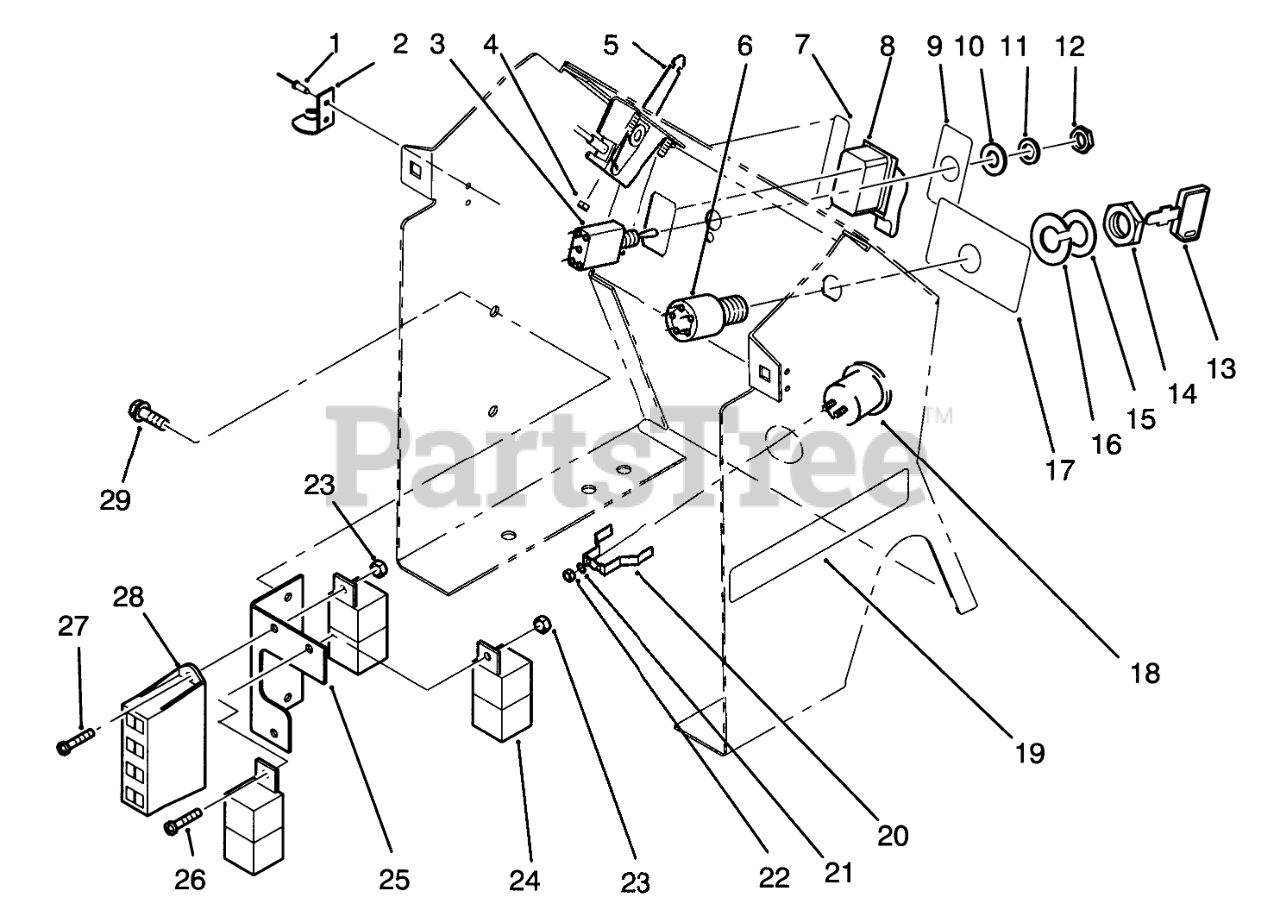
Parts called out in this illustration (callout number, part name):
1	POPRIVET 1/8X 1/8 BK
2	KEEPER-LATCH
3	Switch-Lights (Incl. Ref. #10-14 )
5	CONTROL-THROTTLE
6	Switch-Ignition, Assembly (Incl. Ref #13, 14 & 16)
7	DECAL-PTO
8	PTO-SWITCH W/COVER
9	DECAL-LIGHTS
10	TAB-WASHER
11	Washer
13	KEY-IGNITION
15	Washer
16	LOCKWASHER
17	DECAL-IGNITION
18	HOUR-METER
19	DECAL-MODEL HYDRO
20	CLAMP-HOUR METER
21	WASHER-LOCK
22	Nut
23	Nut
24	RELAY
25	BRKT-FUSE HOLDER B
26	SCREW-PPH
27	SCREW
28	FUSE-HOLDER 4 WAY
29	TRS-1/4-20X1/2 BLACK
